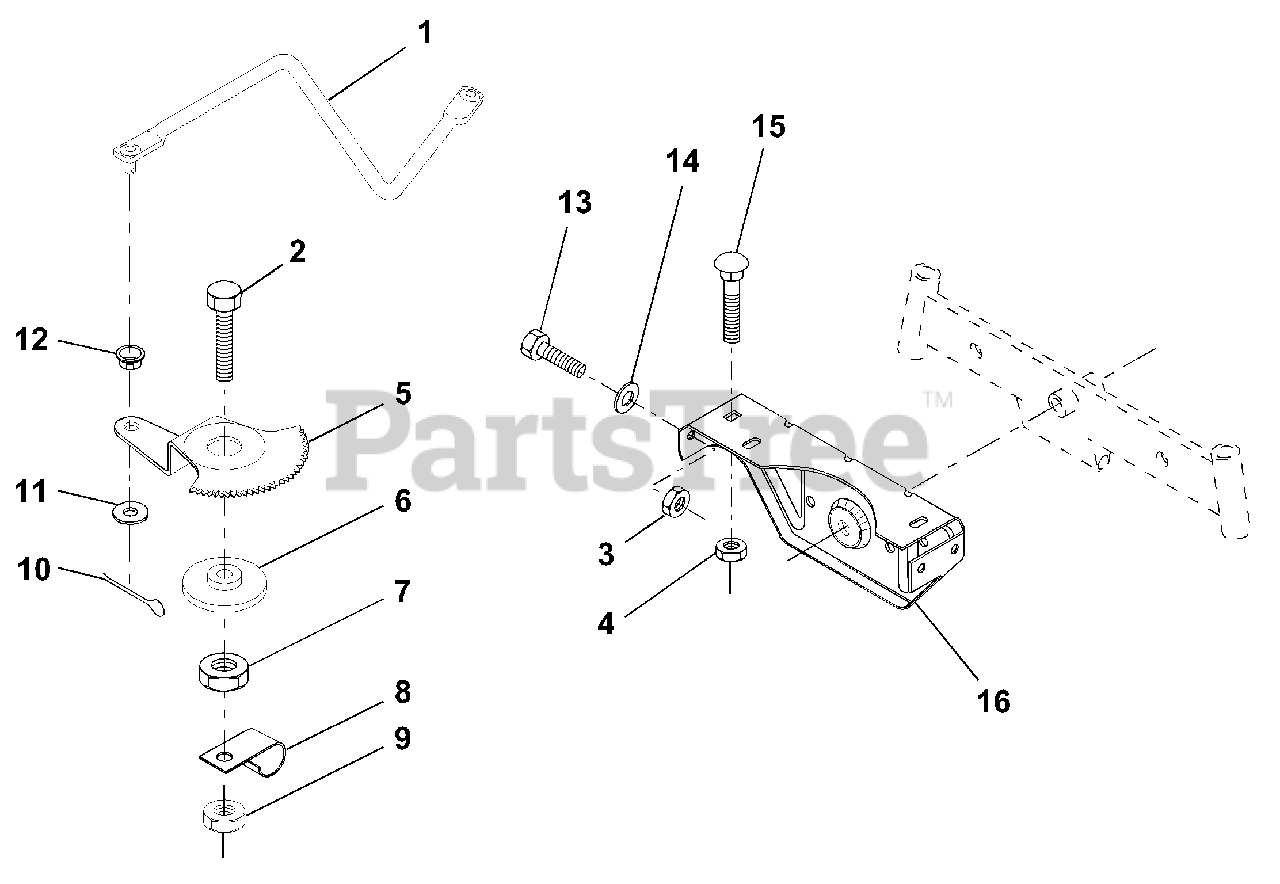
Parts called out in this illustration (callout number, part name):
1	Link, Drag
2	Bolt, Fin Hex 1/2-13 x 1-3/4
5	Gear, Sector
7	Nut, Heavy Hex Top Lock 1/2-13 UNC
8	Clip, Insulated
9	Nut, Crownlock 3/8-16
10	Pin, Cotter 1/8 x 3/4
11	Washer, 13/32 x 13/16 x 16 Ga.
13	Bolt, Hex Hd. 5/16-18 UNC x 3/4
14	Washer 11/32 x 7/8 x 16 Ga.
15	Bolt, Carriage 3/8-16 UNC x 3/4
17	Support, Front Axle
20	Nut, Crownlock 3/8-16 UNC
21	Nut, Crownlock 5/16-18
